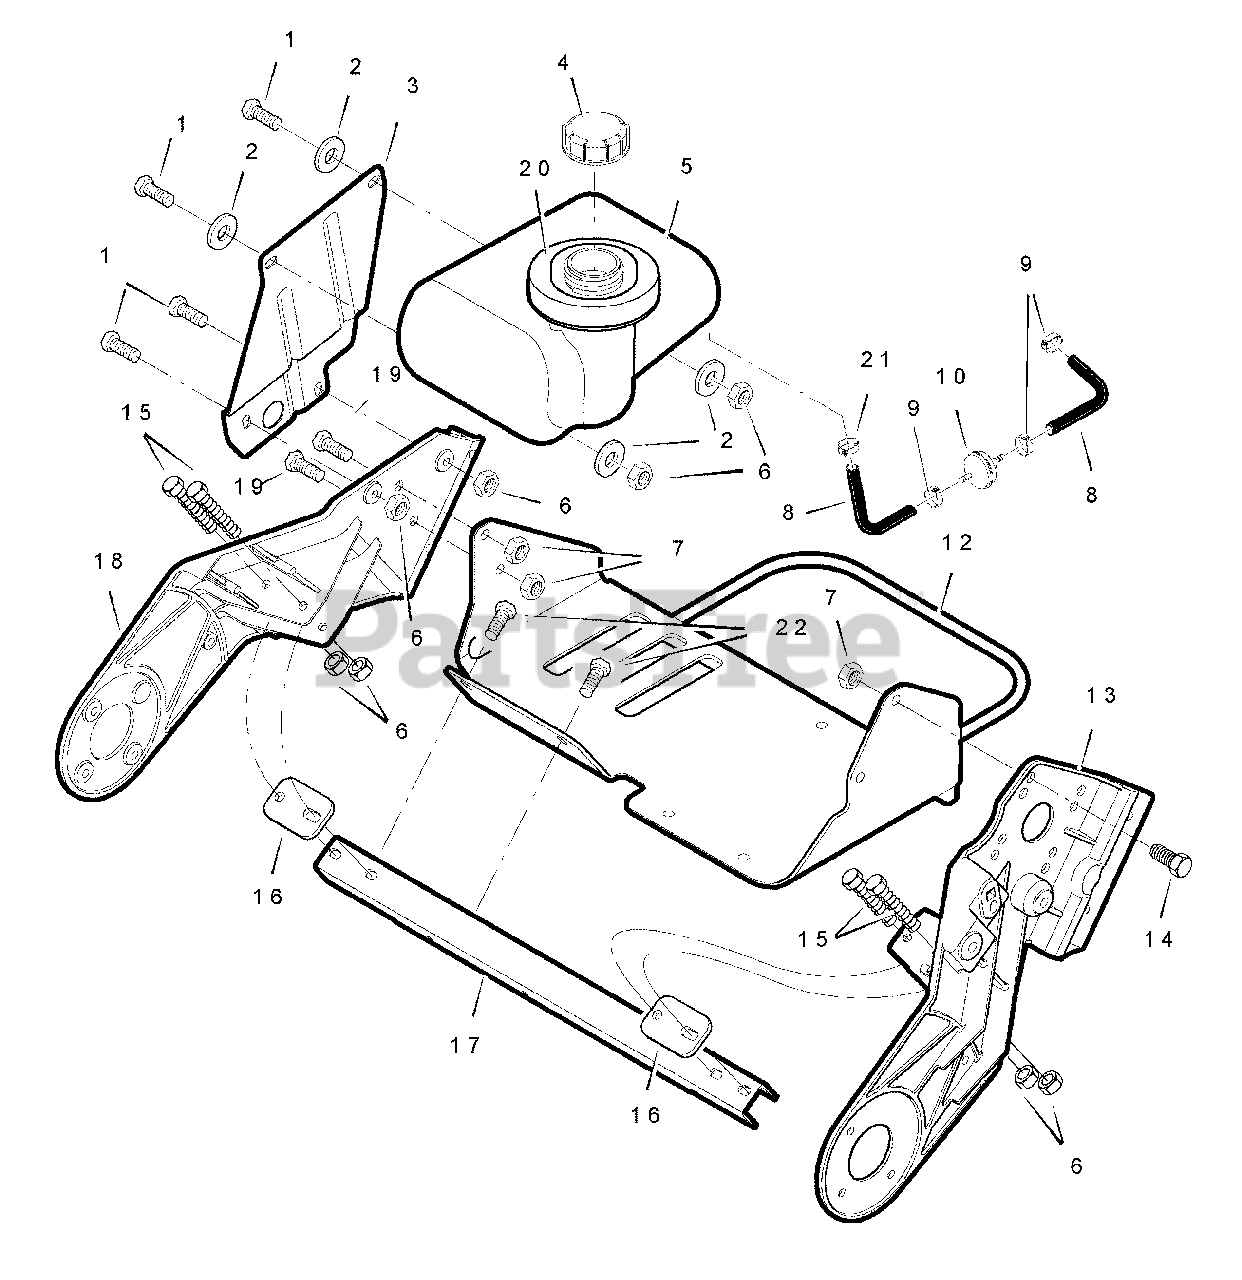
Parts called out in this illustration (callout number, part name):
1	SCREW, 1/4-20 x 3/4
2	WASHER, Flat 9/32 x 5/8 x .065
3	BRACKET, Fuel Tank
4	CAP, Fuel Tank
5	TANK, Fuel
6	NUT, Hex 1/4-20
7	NUT, Hex 5/16-18
8	TUBING, Fuel Line
9	CLAMP, Fuel Line
10	FILTER, Fuel Line
12	CRADLE ASSEMBLY, Engine
13	Frame, Left Hand
14	SCREW, 5/16-18 x .63
15	SCREW, 1/4-20 x 2.00
16	PLATE, Mounting Support
17	SUPPORT, Frame
18	FRAME, Right Hand
19	SCREW, 5/16-18 x 3/4
20	RING, Foam
21	CLAMP, Fuel Line, Screw Type
22	SCREW, 1/4-20 x 5/8
